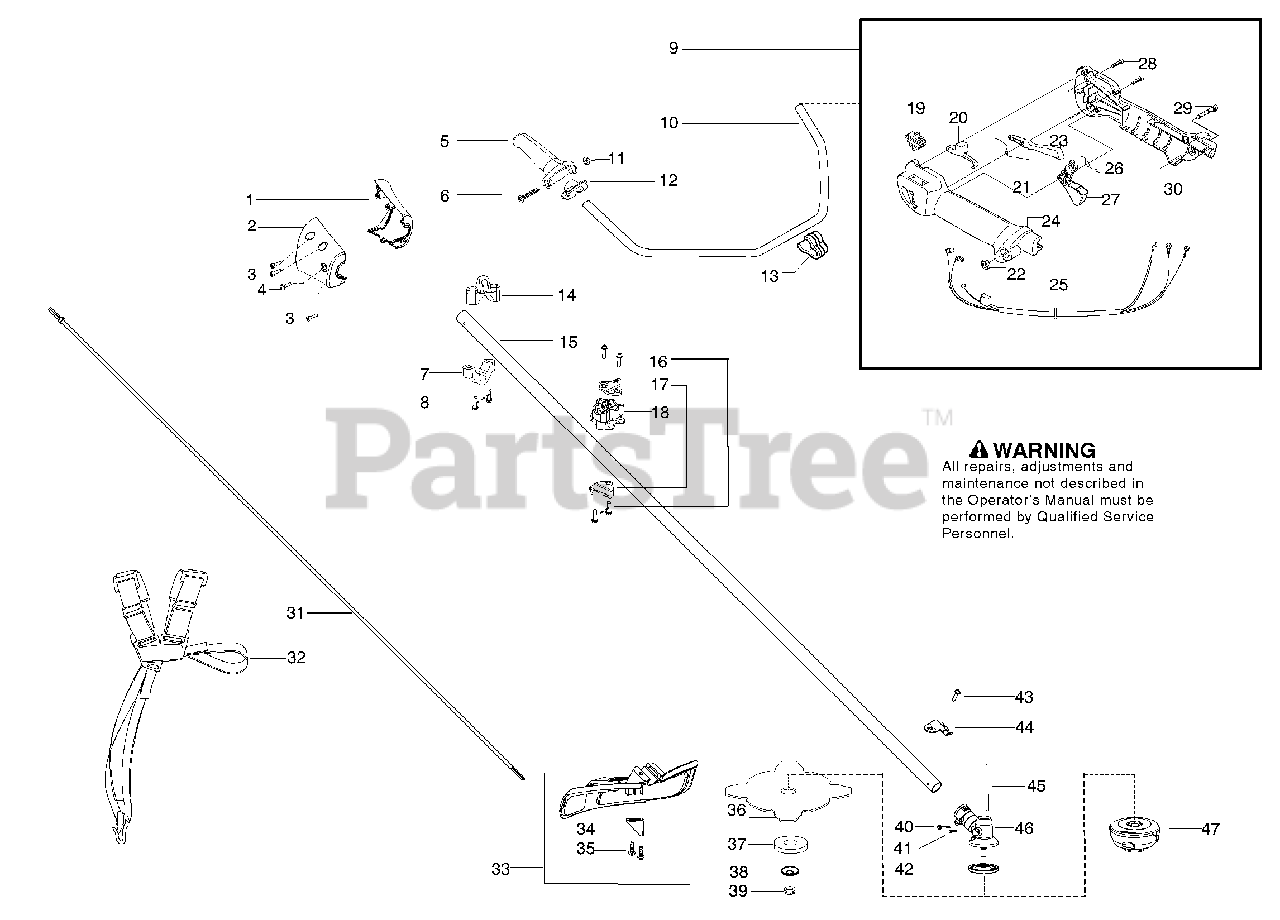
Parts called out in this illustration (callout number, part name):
1	Nose Cone - LH
2	Nose Cone - RH
3	Screw
4	Screw
5	Handle-Assist
7	Clamp-Harness (lower)
9	Assy-Throttle Housing
12	Cover-Assist Handle
13	Clip-Handlebar
14	Clamp-Harness (upper)
15	Kit-Driveshaft
17	Clamp - Bracket
18	Clamp 1" Handlebar
19	Switch-Stop
20	Lockout-Starter Throttle
21	Spring - Lockout
23	Lockout - Throttle
24	Housing - Throttle -LH
25	Assy - Cable Wire
26	Spring - Trigger
27	Trigger - Throttle
29	Screw
30	Housing-Throttle - RH
32	Harness w/o warning
33	Kit-Shield
34	Limiter - Line
36	Blade - Grass
37	Cup-Support
38	Support - Flange
39	Locknut - Blade
42	Driver Disc
44	Bracket - Shield
45	Pin - Locking
46	Assy - Gearbox
47	Assy-T25 Cutting Head
